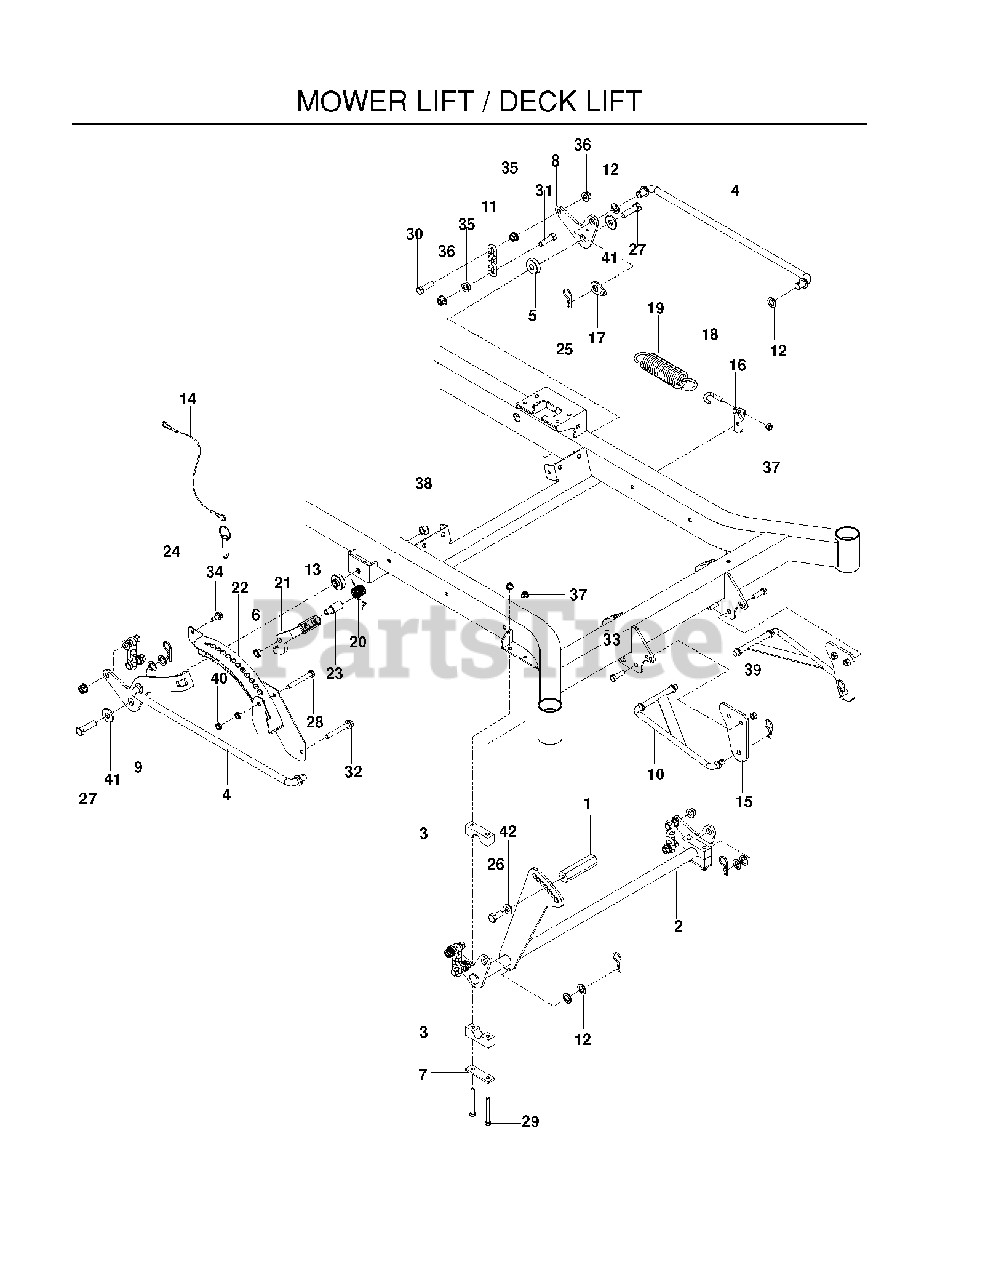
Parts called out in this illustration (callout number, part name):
1	PEDAL, FOOT, HEX
2	SHAFT, FT, LIFT - BLK
3	PILLOW BLOCK
4	CROSS LINK
5	IDLER SPACER
6	SPACER, .3
7	REINFORCEMENT BAR
8	BELLCRANK, RR, LIFT
9	BELLCRANK, RR, RT
10	STRUT LINKAGE
11	LIFT CHAIN - 3 LINK
13	GRIP, TRANSPORT-RELEASE
15	MOUNT, STRUT
16	MOUNT, SPRING
17	TAB, SPRING
20	SPRING, TORSION
21	LATCH, TRANSPORT
22	HEIGHT, ADJUST, DECK
23	PIVOT, LATCH, TRANSPORT
24	PIN, 1/2 X 1 1/2, DETENT RING
25	PIN, COTTER 1 3/4
26	HHCS 1/2-13 X 1
27	HCS 1/2-13 X 1 3/4 GR 8
28	HCS 3/8C X 3
29	HCS 5/16C X 2-3/4
30	HCS 7/16C X 1 1/2
31	HCS 7/16 - 14 X 1 3/4
32	HHFS 3/8-16 X 2 3/4
33	HCS 3/8C X 1 1/4 GR5
34	BOLT 5/16-18 X 3/4
35	NUT 7/16C WHIZ
36	NUT 7/16-14 HEX WHIZ LK
37	5/16-18 NYLOC FLANGE NUT
38	RP NUT 1/2-13 HEX NYLOC ZD
39	NUT 3/8-16 NYLOC
40	NUT HEX 3/8-16 NYLON, THIN
41	WASH USS FLAT 1/2
42	WASHER, 7/16 DISC SPRING
